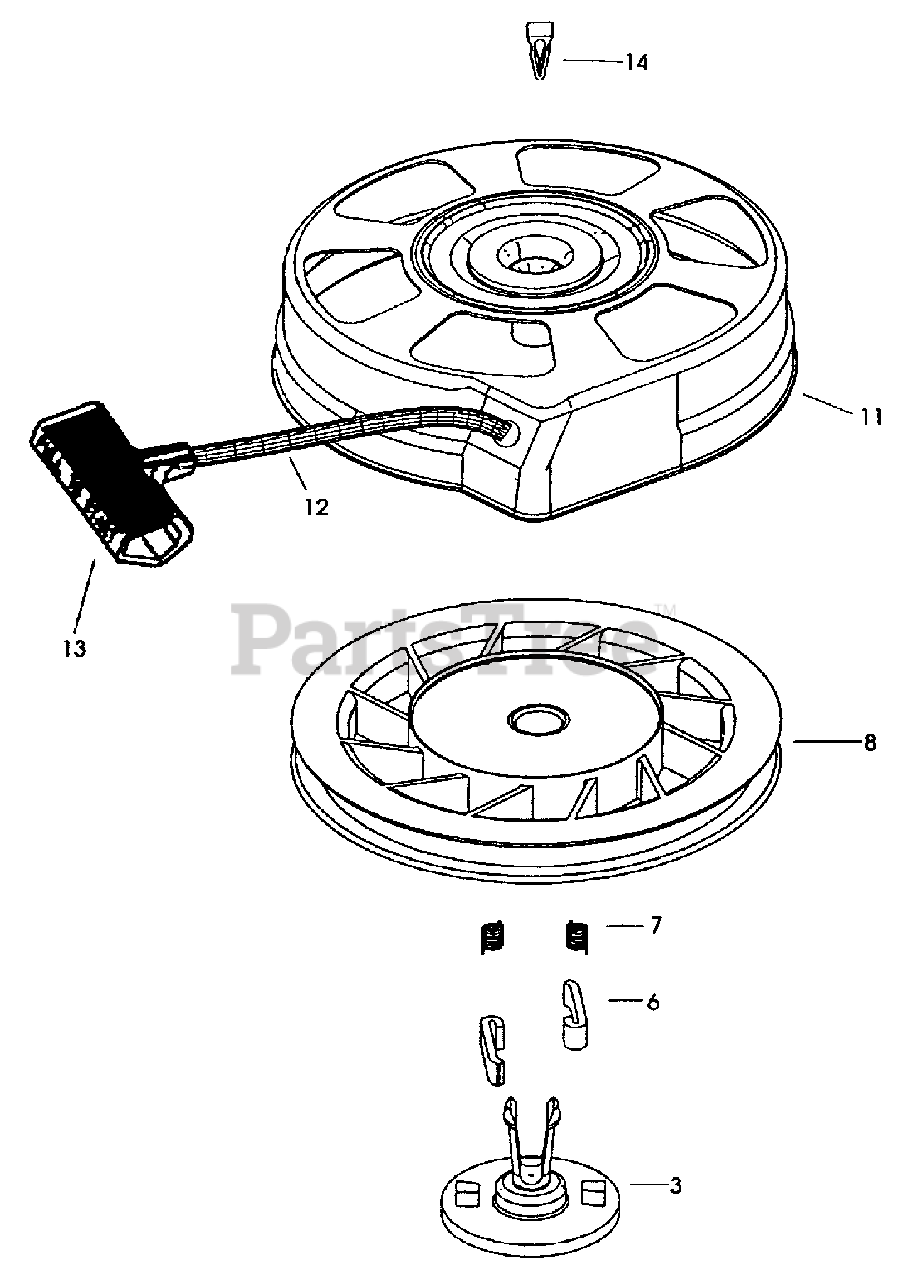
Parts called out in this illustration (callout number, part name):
3	Retainer
6	Dog-Starter
7	Spring-Dog
8	Pulley and Rewind Spring ASM
11	Housing Assembly-Starter
12	Starter Rope ( 98IN X 9/64IN dia.)
13	Handle-Starter
14	Spring Clip
